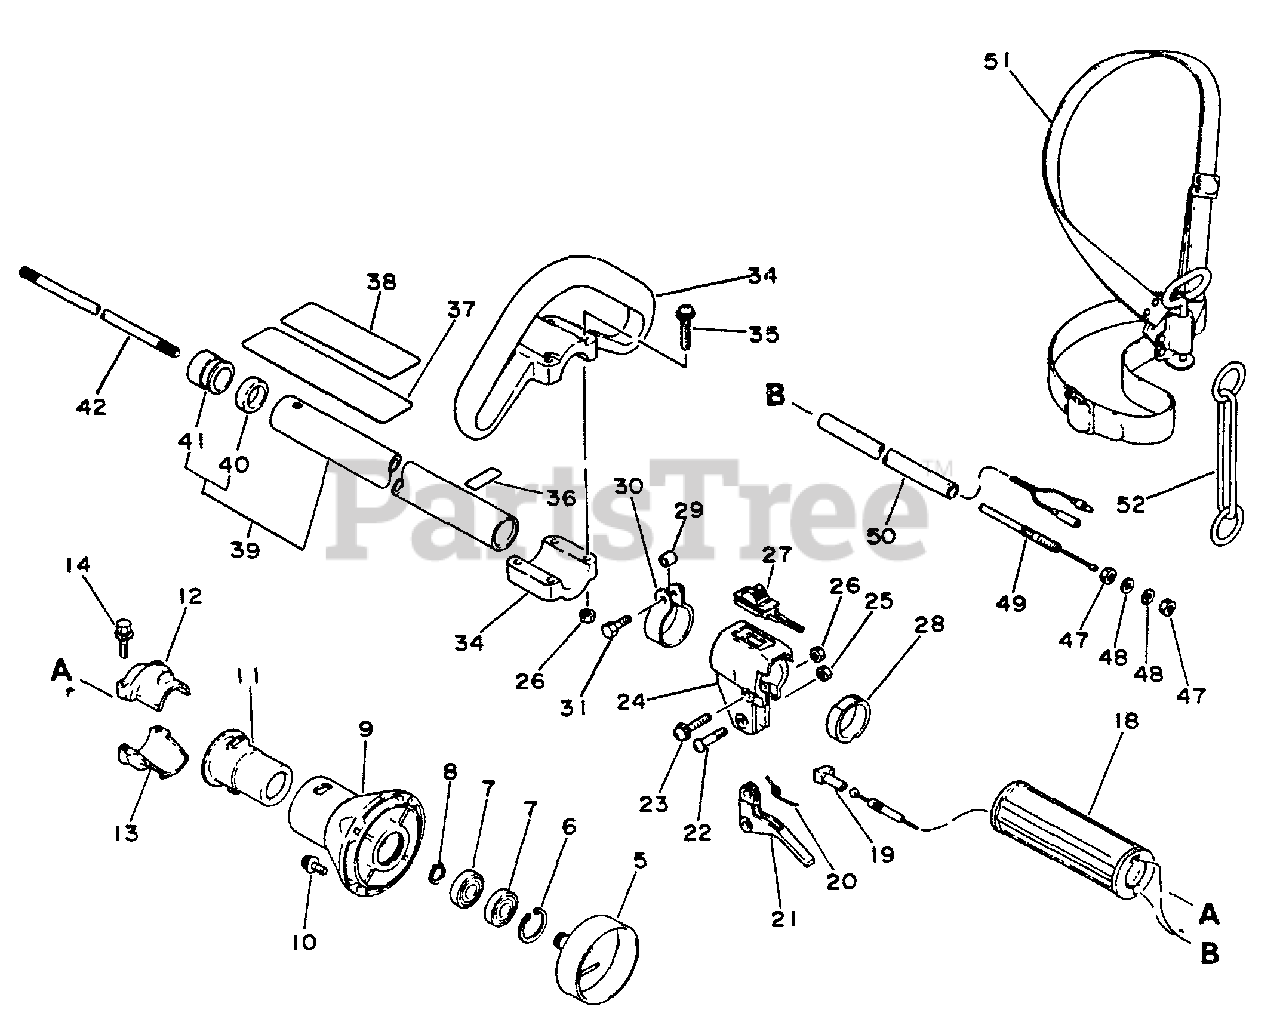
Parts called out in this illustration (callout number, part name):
5	DRUM, CLUTCH
6	RING, RETAINING - 28
7	BEARING, BALL - 6001
8	RING, RETAINING - 12
9	CASE, CLUTCH
10	SCREW - 5X16
12	CLAMP, MAIN PIPE
13	CLAMP, MAIN PIPE
14	BOLT - 5X25
18	GRIP, HANDLE
19	GUIDE, CABLE
20	SPRING, TRIGGER
21	TRIGGER, THROTTLE
22	SCREW - 5X30
23	SCREW - 5X30
24	BRACKET, TRIGGER
25	LOCKNUT - 5
27	IGNITION SWITCH ASSY
31	BOLT - 5X18
34	LOOP HANDLE ASSY
35	SCREW - 5X35
36	LABEL - ALIGNMENT
37	LABEL - CAUTION
38	LABEL - CAUTION
39	MAIN PIPE ASSY
42	DRIVESHAFT - SOLID
48	WASHER - 6
49	CABLE, THROTTLE
50	TUBE - VINYL
51	SHOULDER STRAP ASSY
